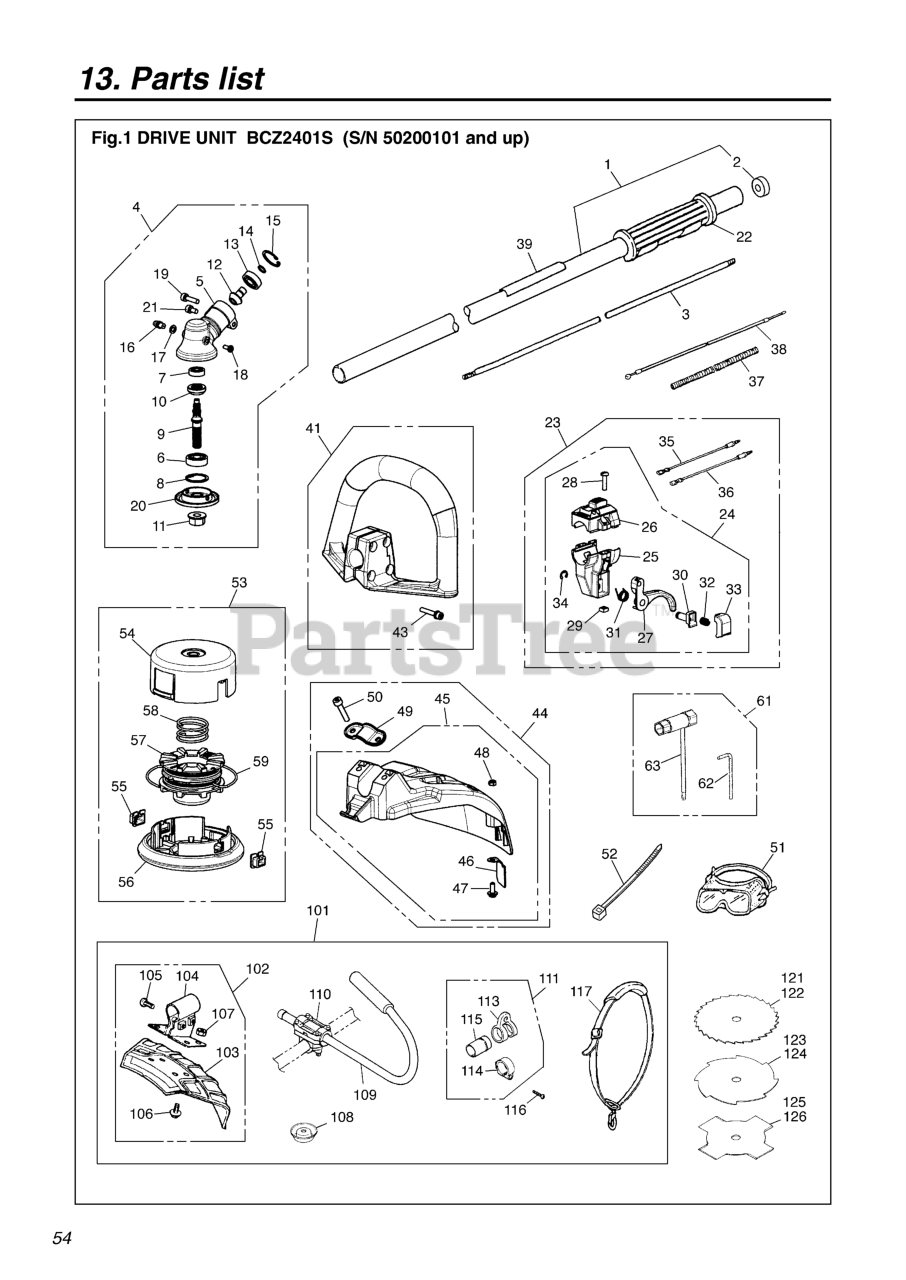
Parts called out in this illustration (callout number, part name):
1	PIPE COMP.
2	SEAL
3	SHAFT (RPLS -12212)
4	GEARCASE ASSY.
5	GEARCASE
6	BEARING
7	BEARING (RPLS T3300-13521)
8	RING, SNAP, M26 X 1.2
9	SHAFT
10	GEAR
11	NUT
12	PINION
13	BEARING (RPLS T3300-13531)
14	RING, SNAP (RPLS T3300-13330)
15	RING, SNAP, M24 x 1.2
16	FITTING, GREASE
17	WASHER, M6 X .8
19	BOLT (RPLS 2850-14220)
20	HOLDER (A)
21	BOLT
22	GRIP (RPLS 3577-32140 & 3220-
23	LEVER ASSY
24	LEVER
26	COVER COMP. (RP. 6110-14410-02)
27	FLEX, TRIGGER
35	CORD (A), BLACK
36	CORD (B), RED
37	TUBE
38	CABLE COMP (RPLS 1633-83100)
39	LABEL, NAME
41	HANDLE ASSY. (REPLACES -14001)
43	SCREW
44	GUARD ASSY. (RPLS -24002)
45	GUARD COMP.
46	BLADE (RPLS T3002-24120)
47	SCREW TORX
48	NUT
49	CLAMP (REPLACES 5807-24120)
50	BOLT, TORX
51	GOGGLE
53	TAP HEAD COMP.
54	CASE (REPLACES -15111)
55	EYELET
56	COVER (REPLACES -15131)
57	HOLDER, CORD (REPLACES-15141)
58	SPRING
59	CORD
61	TOOL SET
62	BAR
63	SOCKET
102	GUARD ASSY.
103	GUARD (ACC.)
105	BOLT
106	SCREW
107	NUT, M6 X 5
108	COVER
109	HANDLE, J
110	BRACKET ASSY (REPLACES -14100)
111	HANGER ASSEMBLY
113	HANGER
114	CLAMP
115	SLEEVE
116	SCREW, M5 x 25
117	STRAP ASSY.
121	BLADE, 9
122	BLADE, 9
123	BLADE, 8
124	BLADE, 9
125	BLADE, 8
126	BLADE, 9
